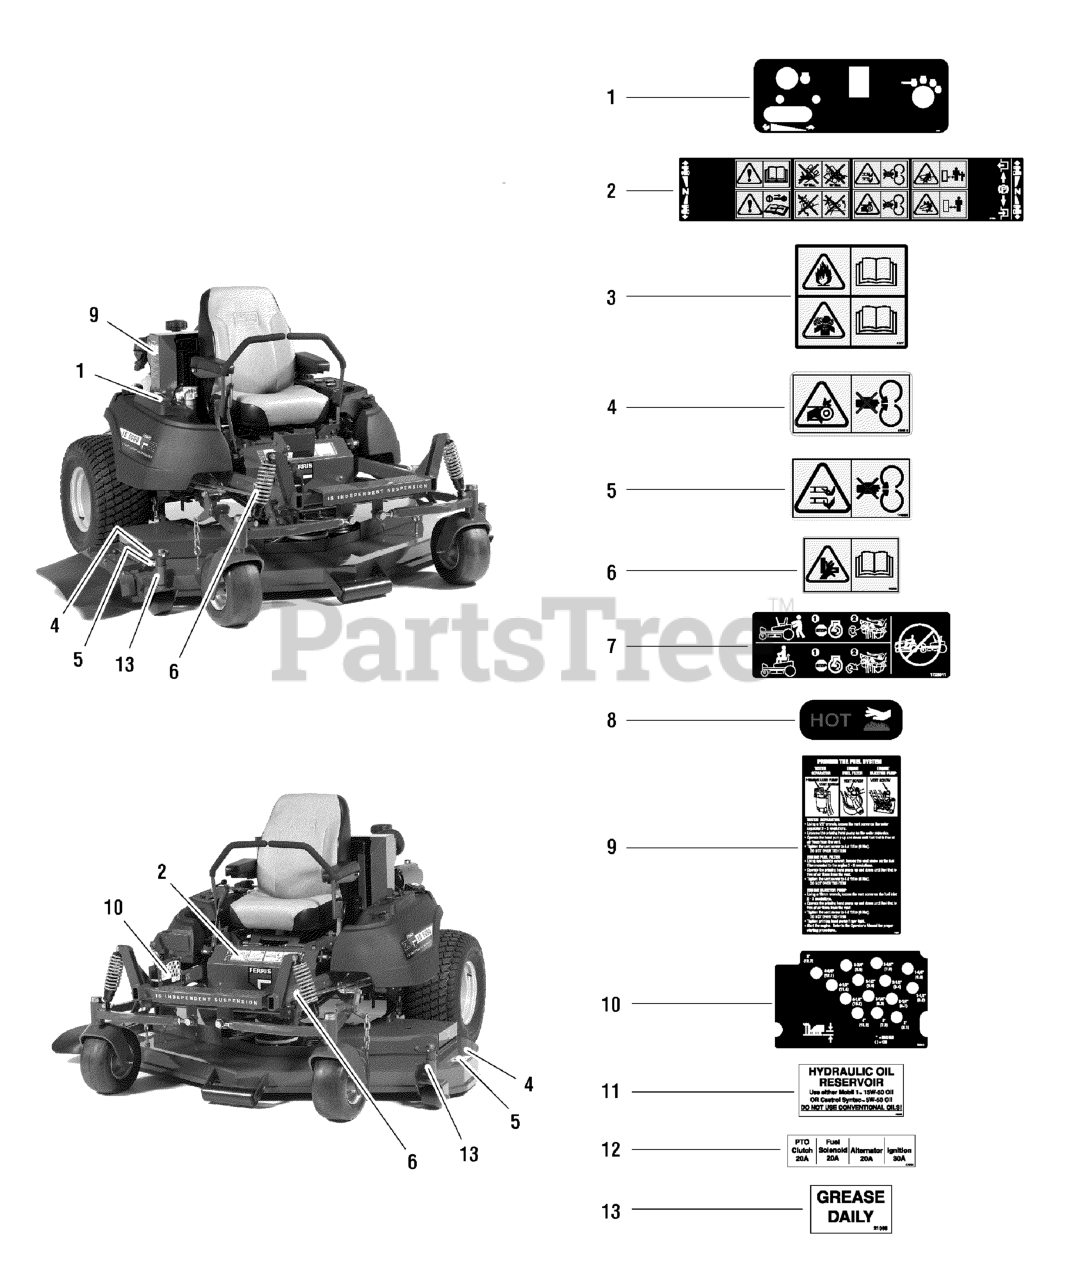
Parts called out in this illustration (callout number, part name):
1	DECAL, Control Panel
2	DECAL, Main, CE
3	DECAL, Danger, Open Flame
4	DECAL, Warning, Hand In Belt
5	DECAL, Warning, Mower
6	DECAL, Pinch Point, CE
7	DECAL, CZT Hydro Release
8	DECAL, Hot Surface
9	DECAL, Priming Instructions
10	DECAL, Deck Height
11	DECAL, Oil Reservoir
12	DECAL, Fuse Location
13	DECAL, Grease Daily
